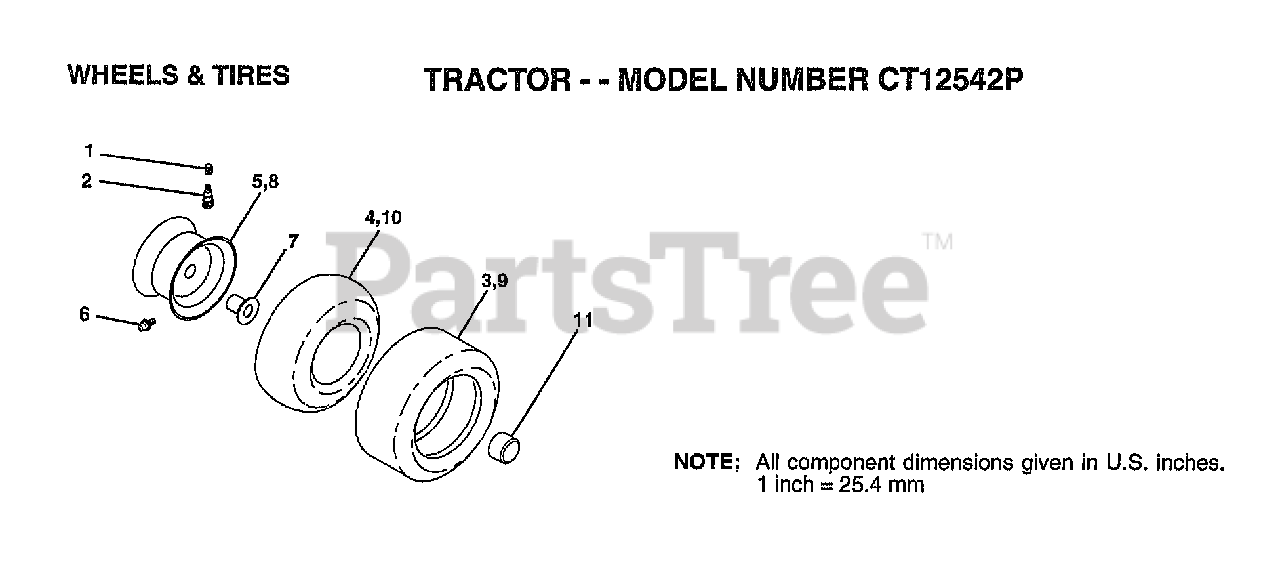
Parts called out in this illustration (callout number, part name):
1	VALVE CAP
2	VALVE STEM LT
4	TUBE.5.3/4.5/6
5	RIM.FRONT.6.YELLO
6	FITTING LT
7	"FLANGE, BEARING"
10	TUBE.18X9.5-8
11	HUB CAP
